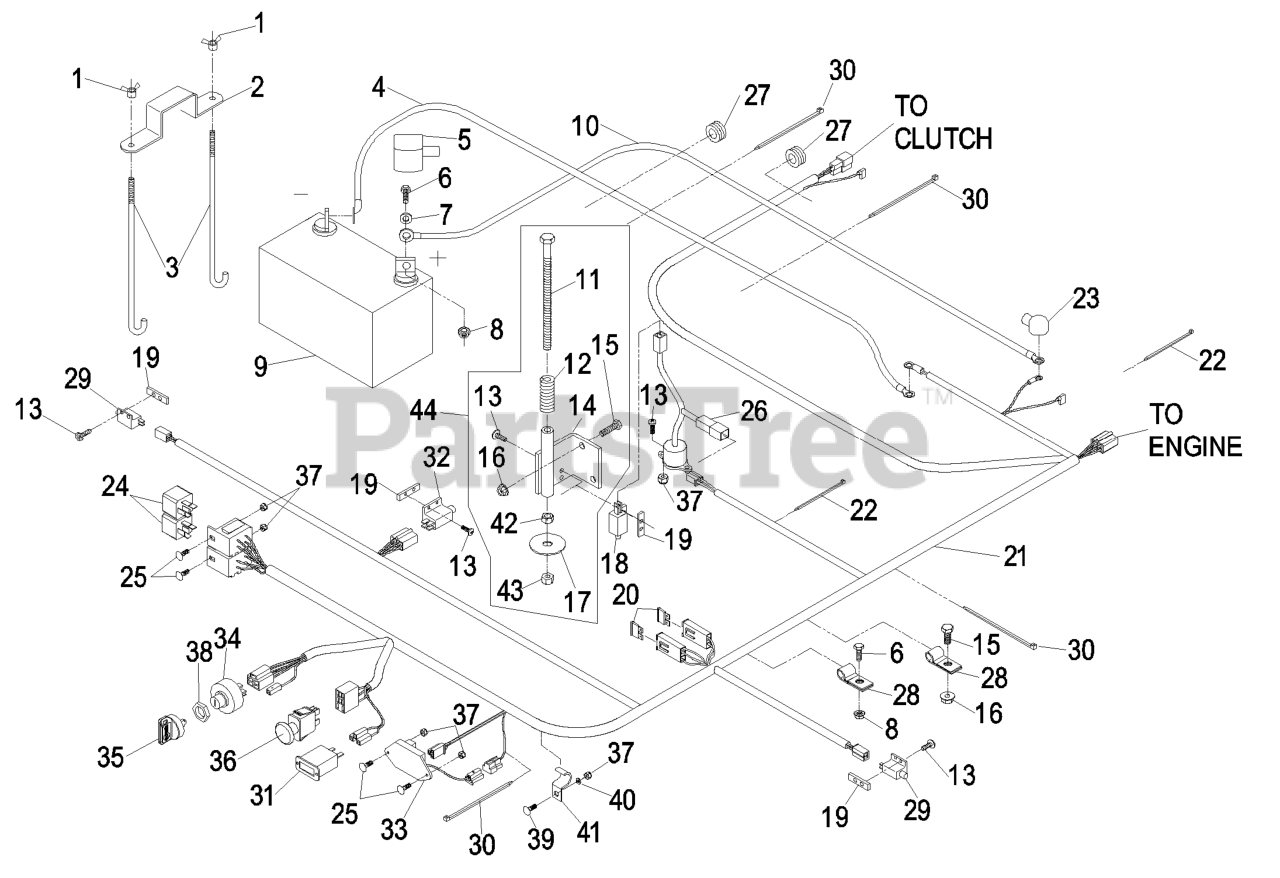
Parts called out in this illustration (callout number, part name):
1	WINGNUT
2	STRAP-HOLDDOWN
3	BOLT-HOLDDOWN
4	WIRE-GROUND
6	SCREW-HH
7	WASHER-FLAT
11	SCREW-HH
12	SPRING-SWITCH, SEAT
13	SCREW-PPH
14	BRACKET-SWITCH, SEAT
15	SCREW-HH
18	SWITCH-CLOSED, NORMALLY
19	PLATE-TAPPED
20	FUSE-BLADE TYPE, 20 AMP
21	HARNESS,WIRE
22	TIE-CABLE
23	INSULATOR-SOLENOID
25	BOLT-CARR
27	GROMMET
28	CLIP-LOOM
29	SWITCH-OPEN, NORMALLY
30	TIE-PLASTIC
31	METER-HOUR
33	MODULE-DELAY, SEAT
35	KEY-IGNITION
37	NUT-LOCK, NI
38	NUT-SWITCH, IGNITION
39	BOLT-CARR
40	WASHER-FLAT
41	CLIP-HALF, LOOM
42	NUT-HEX
43	NUT-LOCK, NI
44	ASM,SEAT SWITCH ACTUATOR
